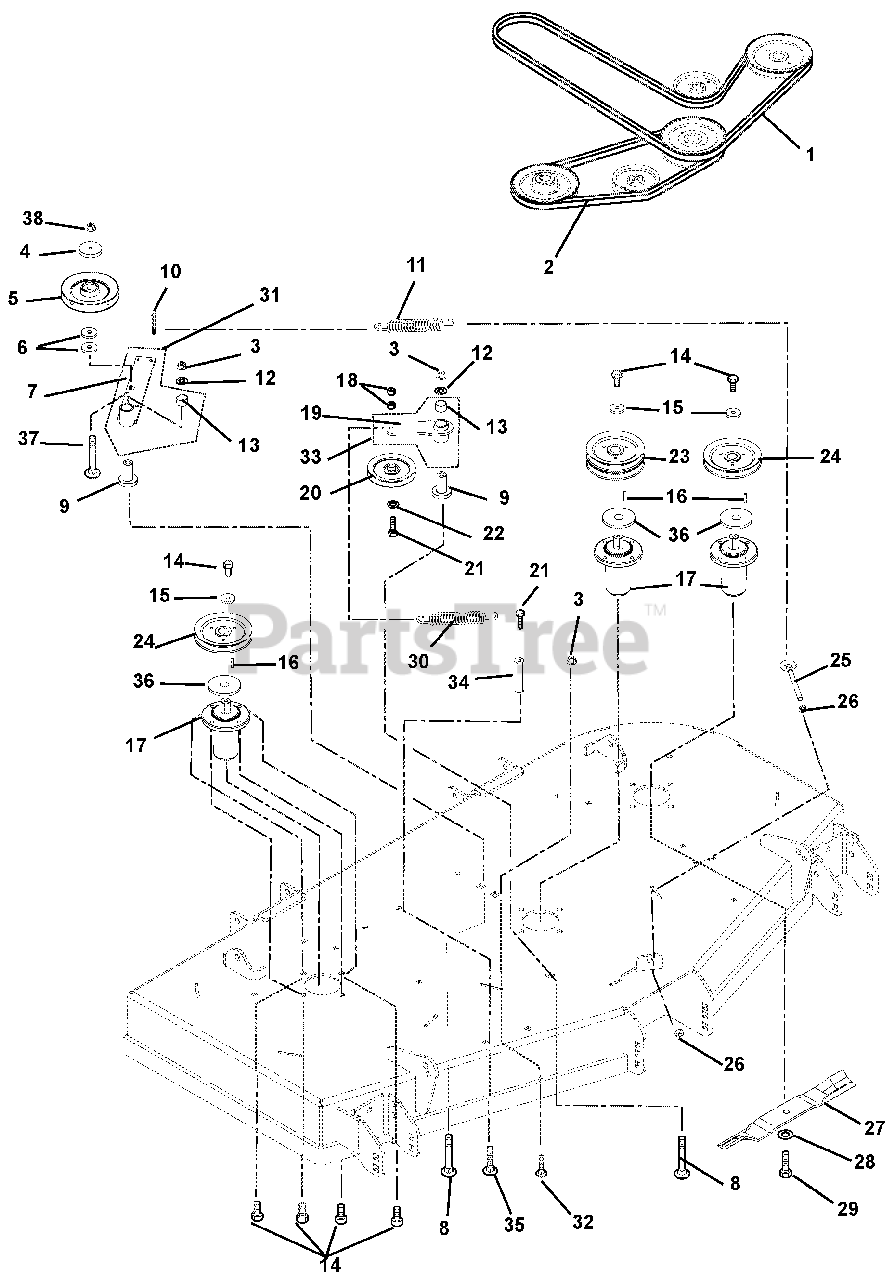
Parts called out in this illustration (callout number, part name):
1	HEX BELT, BB-WRAPPED
2	V-BELT, B-COGGED
3	@NUT-LK-NYL-FLG .50-13 YWZC
4	CAP, IDLER BEARING SEALING
5	PLY-V 6.0 X .500 ID DBL BRG.
5	PLY-V 6.0 X .500 ID SNGL BRG.
6	WSHR-FL-STL .515X1.625X.250 YZ
7	IDLER PIVOT ARM WMT - BLACK
8	@BLT-RHDSSQNK .50-13X3.50 G5YZ
9	BEARING, PEDESTAL
10	BLT,SHLDR EP .38-16X.30 HEX YZ
11	SPRING, EXTENSION
12	WSHR-FL-STL .531X1.250X.10 YWZ
13	BSHG, 1.00 X 1.125 X 1.937
14	BLT-HEX .38-16X1.0 GR8 YZ EP30
15	WSHR,FLT STL.406X1.50X.245YWZC
16	KEY, SQ .25X.25X1.00 RC 40-50
17	ASSEMBLY, SPINDLE
18	@NUT-LK-CTR .38-16 YWZC
19	WMT, IDLER PIVOT ARM
20	ASM, V-IDLER 5.00 O.D.
21	@BLT-HEX .38-16X2.25 GR5 YWZC
22	@WSHR-FL-STL.406X.812X.065 YWZ
23	SHEAVE, DOUBLE 1"ID X 6.00"OD
23	SHEAVE, DOUBLE 1"ID X 6.75"OD
23	SHEAVE, DOUBLE 1"ID X 8.25"OD
24	SHEAVE, SINGLE 1"ID X 6.00" OD
24	SHEAVE, SINGLE 1"ID X 6.75"OD
24	SHEAVE, SINGLE 1"ID X 8.25"OD
25	BOLT, .38-16X4.50 .62 DIA EYE
26	NUT-HEX-JAM .375-16 YWZC
27	BLADE, MULCH 18.00"
27	BLADE, MULCHING (20.50")
27	BLADE,MOWER-72"MULCH(24.5"LG)
28	WSHR-BLVL .669X1.535X.138
29	BLT-HEX .62-18X1.75 GR8 YWZC
30	SPRING, EXTENSION
31	ASSEMBLY, PTO IDLER PIVOT ARM
32	BLT-RDHDSHSQNKFT.50-13X1.50 G5
33	ASM, IDLER PIVOT ARM
34	NUT COUPLING .375-16X1.75
35	@BLT-RDHDSHSQNK.38-16X1.0 G5YZ
36	RETAINER, GREASE
37	@BLT-RDHDSQNK .50-13X3.00 G5YZ
38	@NUT-LK-CTR .50-13 YWZC
